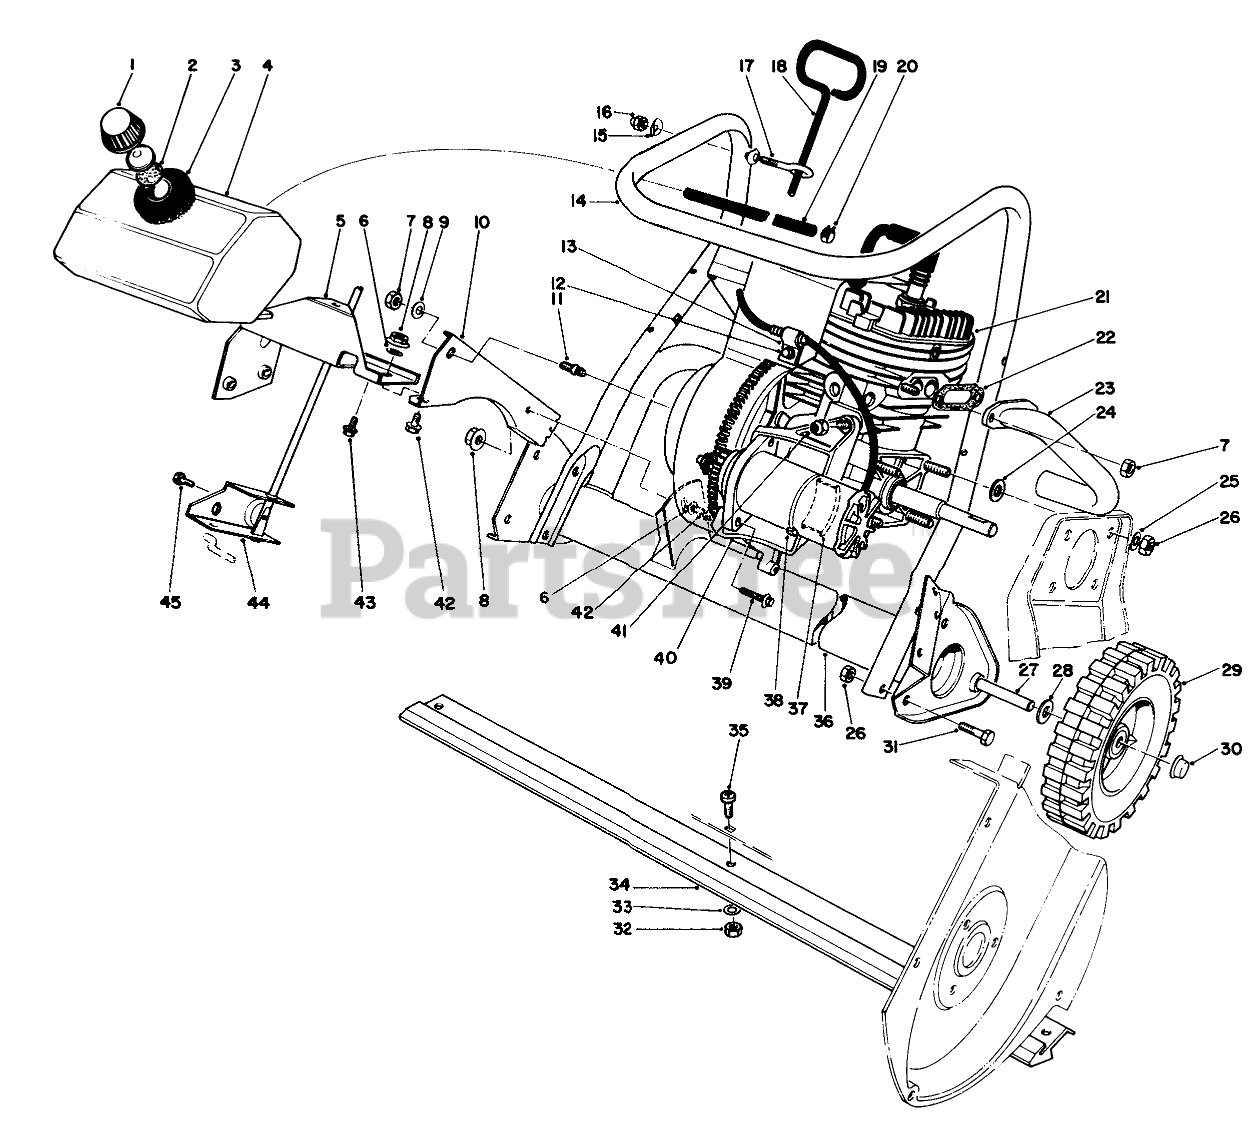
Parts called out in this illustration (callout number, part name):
1	Gas Cap Assy. (Incl. Ref. #2)
2	GAS CAP GASKET
3	FOAM PAD
4	GAS TANK
5	Support-Gas Tank
6	WASHER-LOCK
7	NUT-LOCK, CONE
9	GRILLE HINGE SPACER
10	ENGINE SUPPORT
12	SCREW-HWH
13	CABLE CLAMP
14	HANDLE-LOWER
15	WASHER
16	NUT-CAP
17	EYEBOLT
18	ADJ ROD ASM
19	GasLine
20	Clamp
22	EXHAUST GASKET
23	EXHAUST PIPE
24	WASHER-FLAT
25	WASHER-PLAIN
26	NUT-LOCK, NI
28	WASHER-FLAT
29	WHEEL
30	RETAINER-PUSH ON
31	SCREW-HH
32	NUT-LOCK, NI
33	WASHER-FLAT
34	SCRAPER
35	SCREW-PPH
36	MUFFLER ASSEMBLY
37	RR MOTOR SUPPORT
38	TIE-CABLE
39	SCREW-FLOW, TAPTITE
40	MOTOR MTG BRKT
41	NUT-LOCK, NI
42	5/16-18X.62 WHIZLOK SCR
43	SCREW-HWH
44	VANE ADJ BRKT
45	SCREW-TAPTITE
